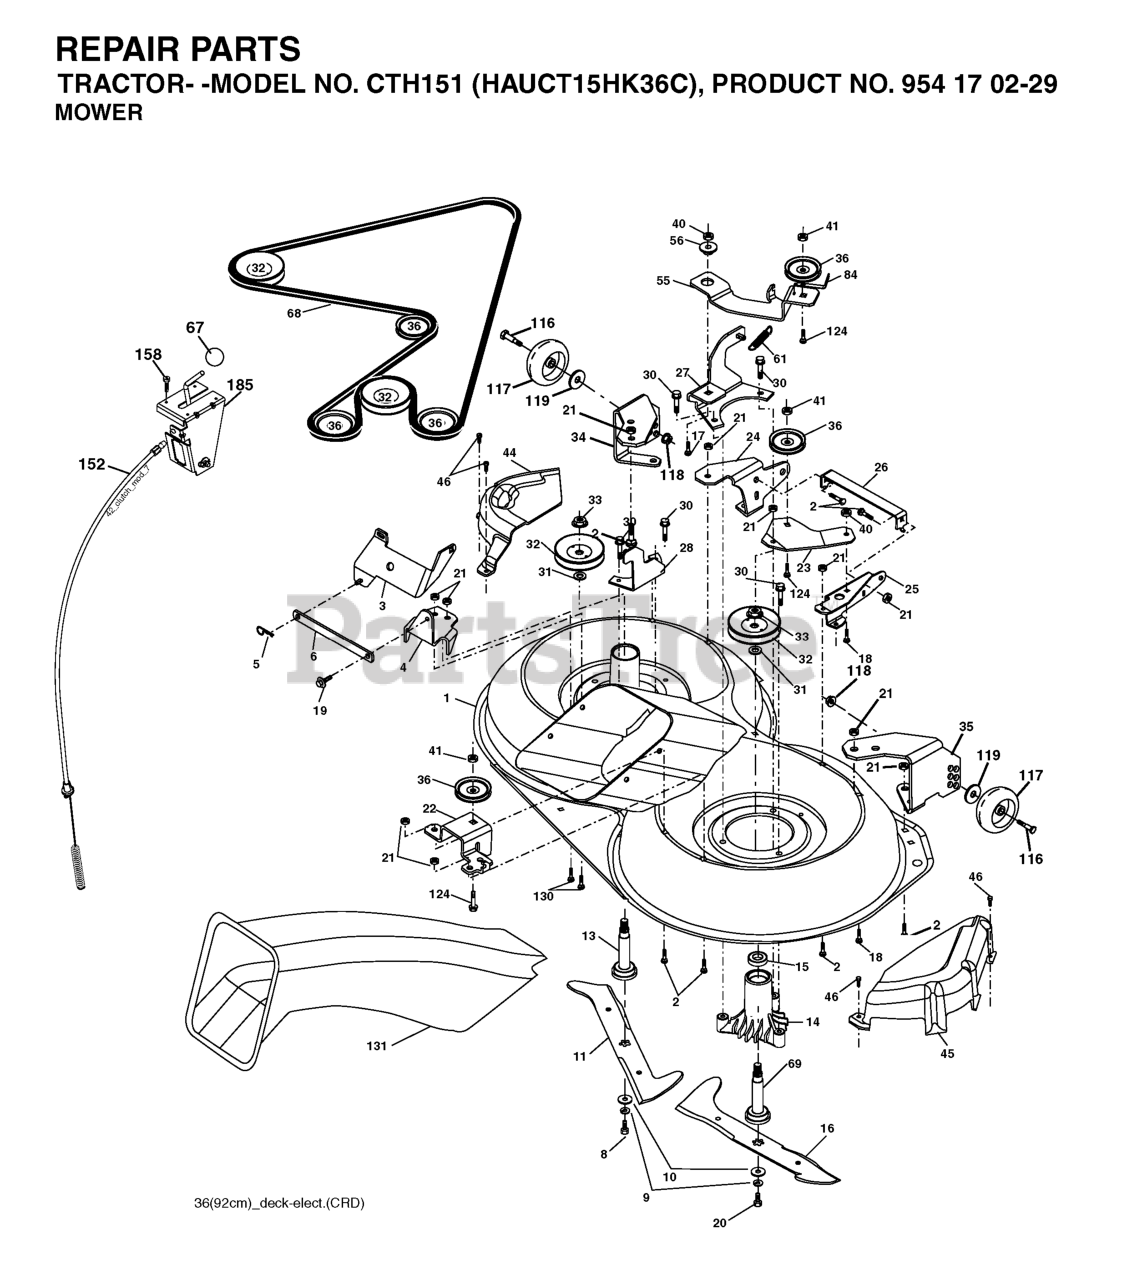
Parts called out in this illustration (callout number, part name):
1	MOWER HOUSING, DECK
2	RP BOLT 5/16-18 X3/4 ZN/YEL GR
5	RETAINER-SPRNG RB
6	BAR.SWAY.92.CRD
8	BOLT.3/8-24X1.25 GR8
9	LOCKWASHER
10	WASHER.BLADE
13	SHAFT ASM VENT
14	HOUSING.MANDREL.VENTED (MACHD)
17	BOLT.3/8-14X1.25
19	BOLT SHD 5/16-18
20	BOLT.3/8-24X1.25GR8. LHTHRD
21	LOCKNUT
26	BRACE.SUPT.SUSP.FRT.CRD
30	SCREW, WASHER HEAD
31	WASHER.SPACER.MANDREL
32	PULLEY, MANDREL
33	NUT, FLG TOPLOCK 9/16"
36	PULLEY.IDLER.4.25
41	NUT LOCK FLG 3/8-16 UNC
45	COVER.MANDREL.RH.CRD
46	SCREW.1/4-20X5/8
56	SPACER.RETAINER.MOWER
61	SPRING.TENSION.BELT
67	KNOB T (3/8 HOLE)
68	HEX-BELT
69	SHAFT.ASM.W/LWR.BRG.RH.THREAD
84	KEEPER, BELT IDLER
116	SHOULDER BOLT
117	WHEEL GAGE DONUT
118	LOCKNUT
119	WASHER.5/16.FLAT.STE.STD.
124	BOLT.3/8-16X1.50
130	BOLT.CARR.SQNK.5/16-18UNC.X3/4
131	CHUTE BAGGER
158	SCREW
185	HEAD ASM. CABLE CLUTCH
